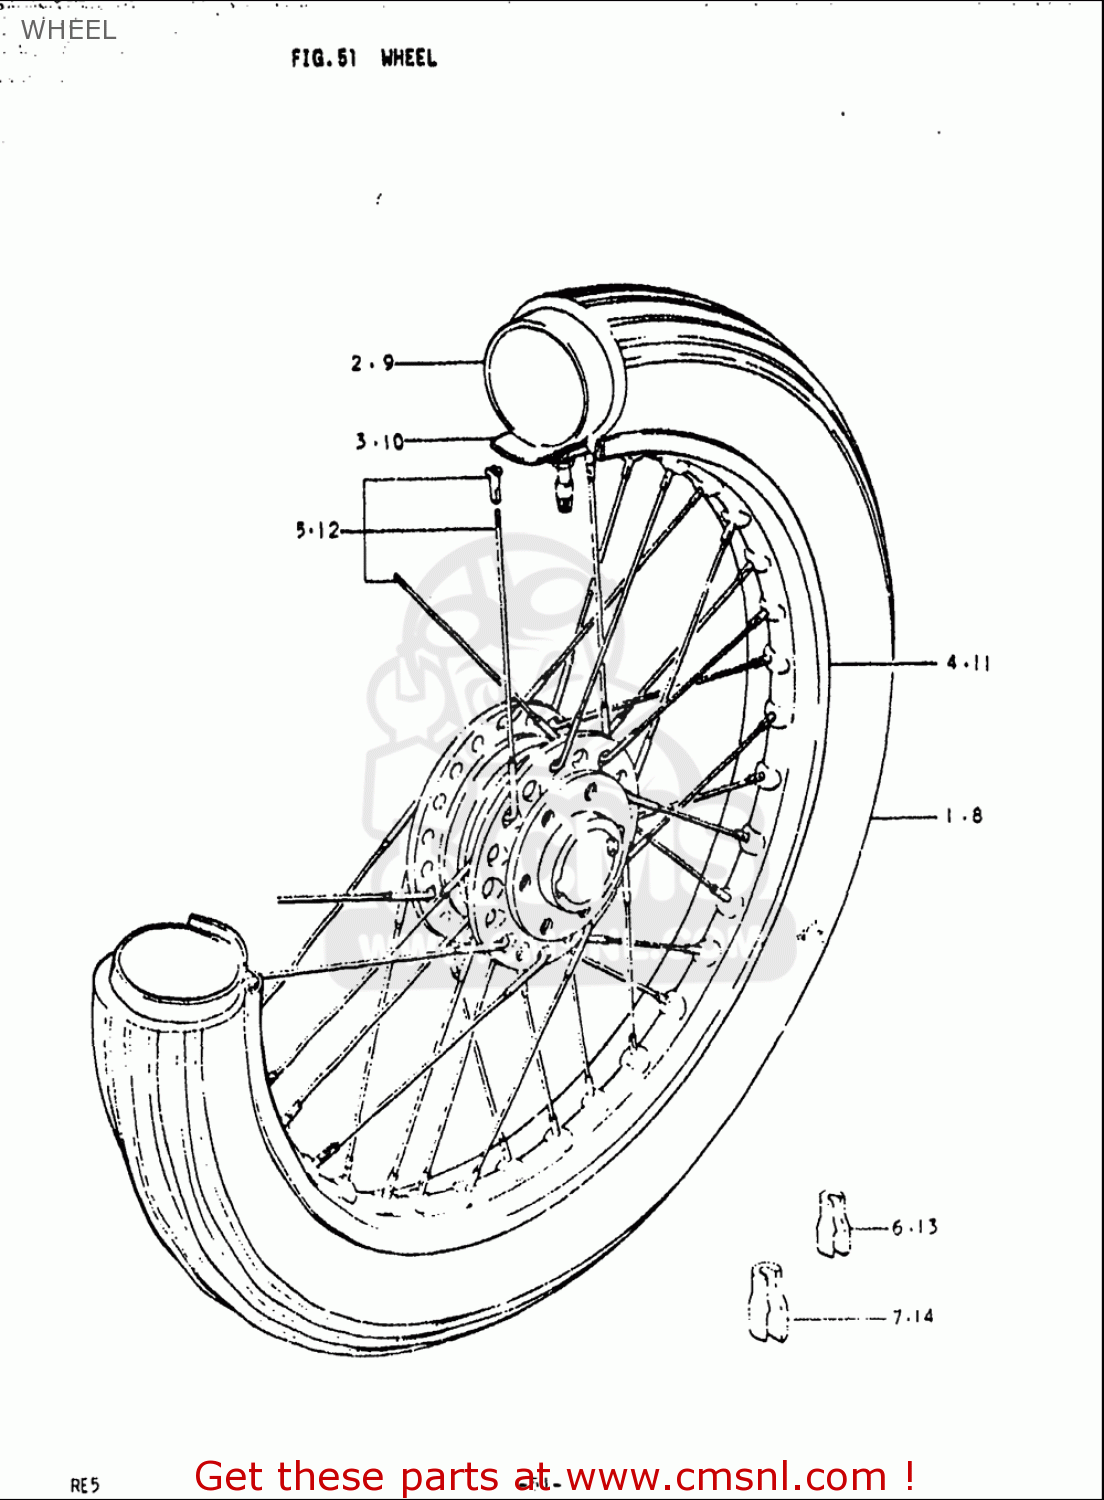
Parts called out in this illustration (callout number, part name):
2	TUBE ASSEMBLY,WHEEL,INNER
3	PROTECTOR,WHL INR TUBE
5	SPOKE ASSY,FR
6	BALANCER,WHEEL (B)
7	BALANCER,WHEEL (30G)
9	TUBE,INNER
10	PROTECTOR,INNER TUBE
12	SPOKE SET,RR WHEEL
13	BALANCER,WHEEL (B)
14	BALANCER,WHEEL (30G)
